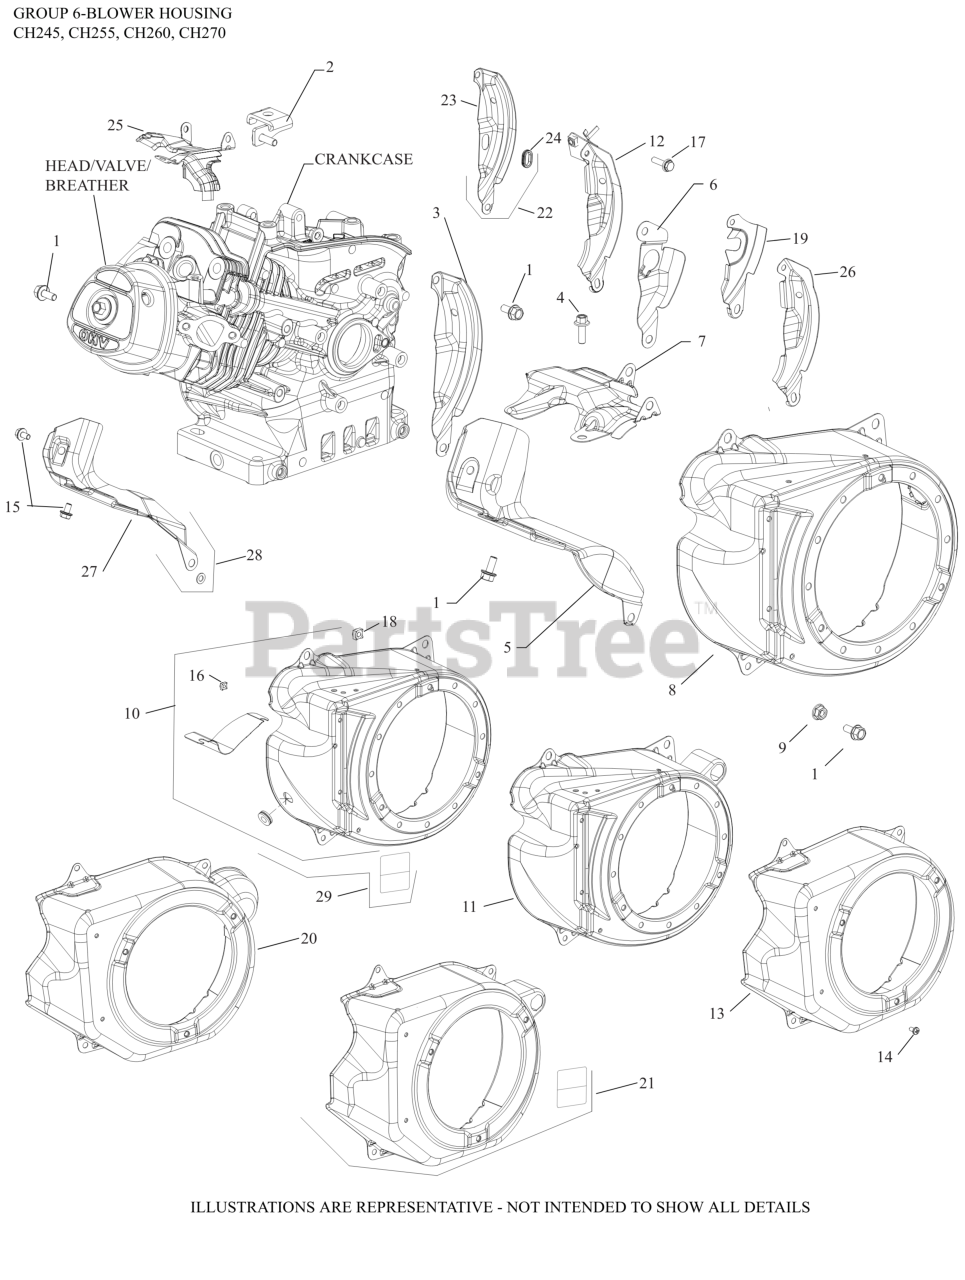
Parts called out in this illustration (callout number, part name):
1	SCREW, HEX FLANGE (M6)-USE 25 086 433-S
3	SHIELD, FLYWHEEL
4	SCREW, M6 X18
5	SHIELD, CYLINDER HEAD
7	SHIELD, UPPER HEAT
8	HOUSING, BLOWER
9	NUT, HEX FLANGE (M6) - USE 14 100 16-S
10	KIT, BLOWER HOUSING
16	NUT, BLOWER HOUSING (CKY)-(#DSC)
18	NUT, BLOWER HOUSING (CKY)-(#DSC)
